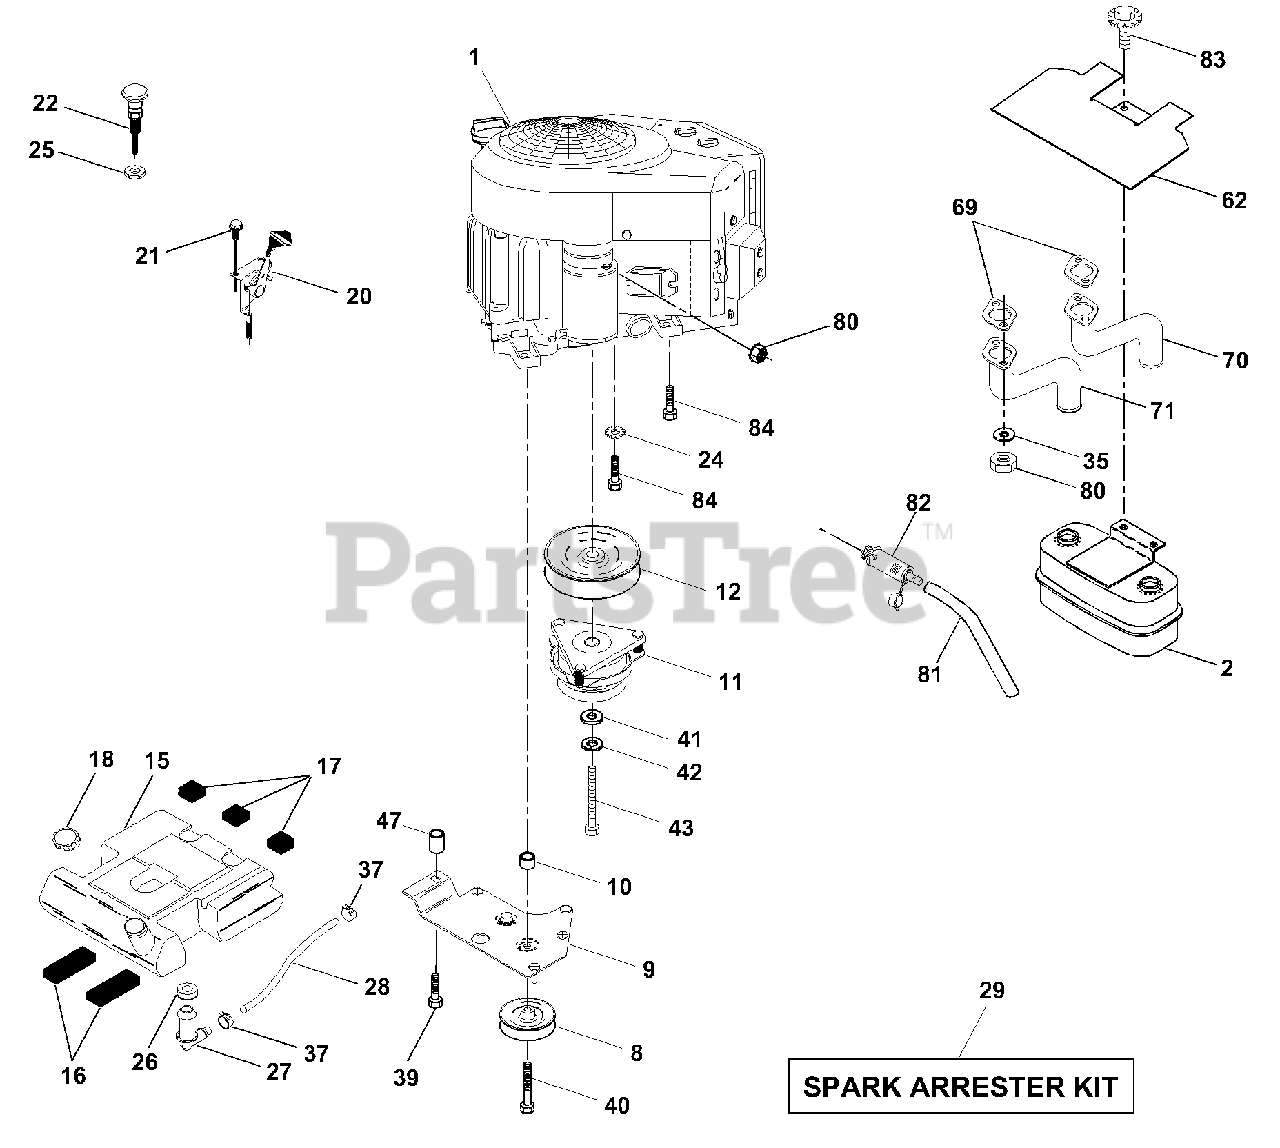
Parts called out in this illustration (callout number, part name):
2	Muffler Side
8	Pulley V-Idler
9	Keeper Asm. Belt Engine VGT
11	Clutch Electric
12	Pulley Engine VGT Elect Clutch
15	Tank Fuel Rear 3.50
16	Pad Spacer
17	Pad Spacer
20	Control Throttle
21	Screw Hex Thd Cut 1/4 - 20 X 5/8
22	Control Choke
24	Washer Ext Tooth 3/8
25	Nut Keps 3/8-24 Unf
27	Stem Tank Fuel
28	Fuel Line
29	Spark Arrester Kit
37	Clamp Hose
39	Screw TT 3/8-16 x 2-1/4 UNC
40	Screw TT 3/8-16 x 4 UNC
41	Washer 1-1/2 OD X 15/32 ID X .250
42	Washer Lock 7/16
43	Bolt Hex 7/16-20 X 4-1/4 Ga 5
62	Shield Heat Muffler
70	Tube Exhaust LH
71	Tube Exhaust RH
80	Nut Flange M8-1.25
81	Tube Drain Oil Easy
82	Plug Oil Drain Easy
83	Bolt 5/16-18unc X 1-3/4 W/Sems
84	Screw 3/8-16 x 1-1/2
